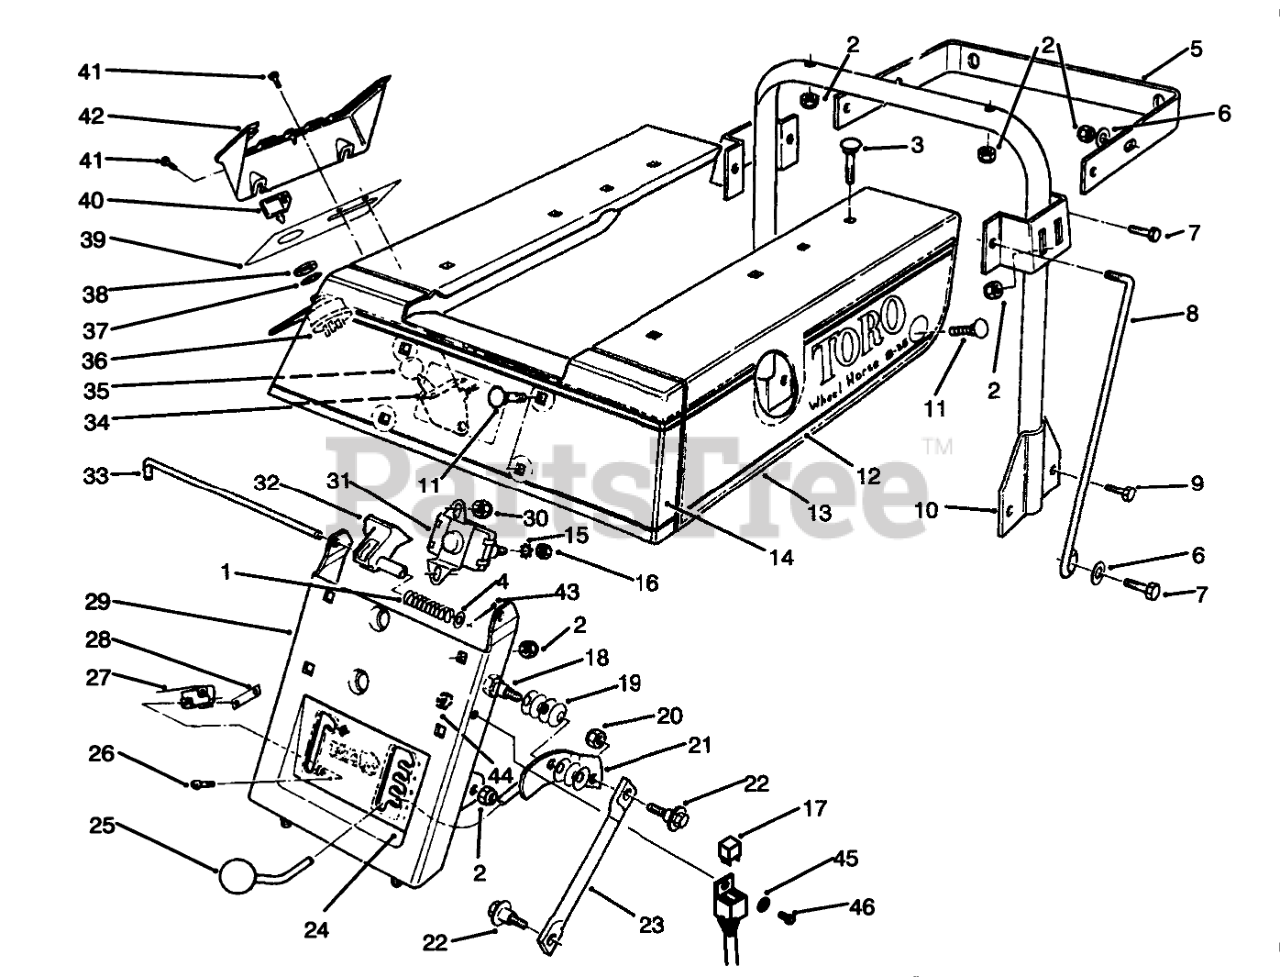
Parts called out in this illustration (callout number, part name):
1	SPRING-COMPRESSION
2	NUT-LOCK, NI
3	SCREW-CARR
4	WASHER-FLAT
5	STANDBAR
6	WASHER-PLAIN
7	SCREW-HH
8	BRACE-SEAT SUPPORT
9	SCREW-HH
10	SEAT SUPT WA (BLACK)
11	SCREW-CARR
12	DECAL - LH 825 TORO
13	SEAT BODY WA (RED)
14	DECAL - FRONT TORO
15	WASHER-LOCK/EXT
16	NUT-JAM
17	RELAY
18	BOLT-SHOULDER
19	WASHER-BELLEVILLE
20	NUT-LOCK, NI
21	HOC HDLE WA
22	BOLT-SHOULDER
23	LINK-HOC
24	DECAL - HOC/DECK ENGAGE
25	KNOB-CONTROL
26	SCREW-SPH
27	SWITCH-MICRO
28	NUT-SPEED
29	FRT SEAT SUP WA RED
30	NUT-LOCK, NI
31	SOLENOID
32	PROP-SEAT
33	ROD-SEAT BASE
34	CONTROL-THROTTLE
35	Knob
36	Switch-Ignition (Incl. Ref. #37 & 38)
37	WASHER-TOOTH, INTERNAL
38	NUT-HH
39	DECAL - CONTROL PANEL
40	KEY-IGNITION
41	SCREW-THD FORM, HWH
42	COVER-CONTROL PLATE
43	SCREW-HSH
44	NUT-LOCK, NI
45	WASHER-FLAT
